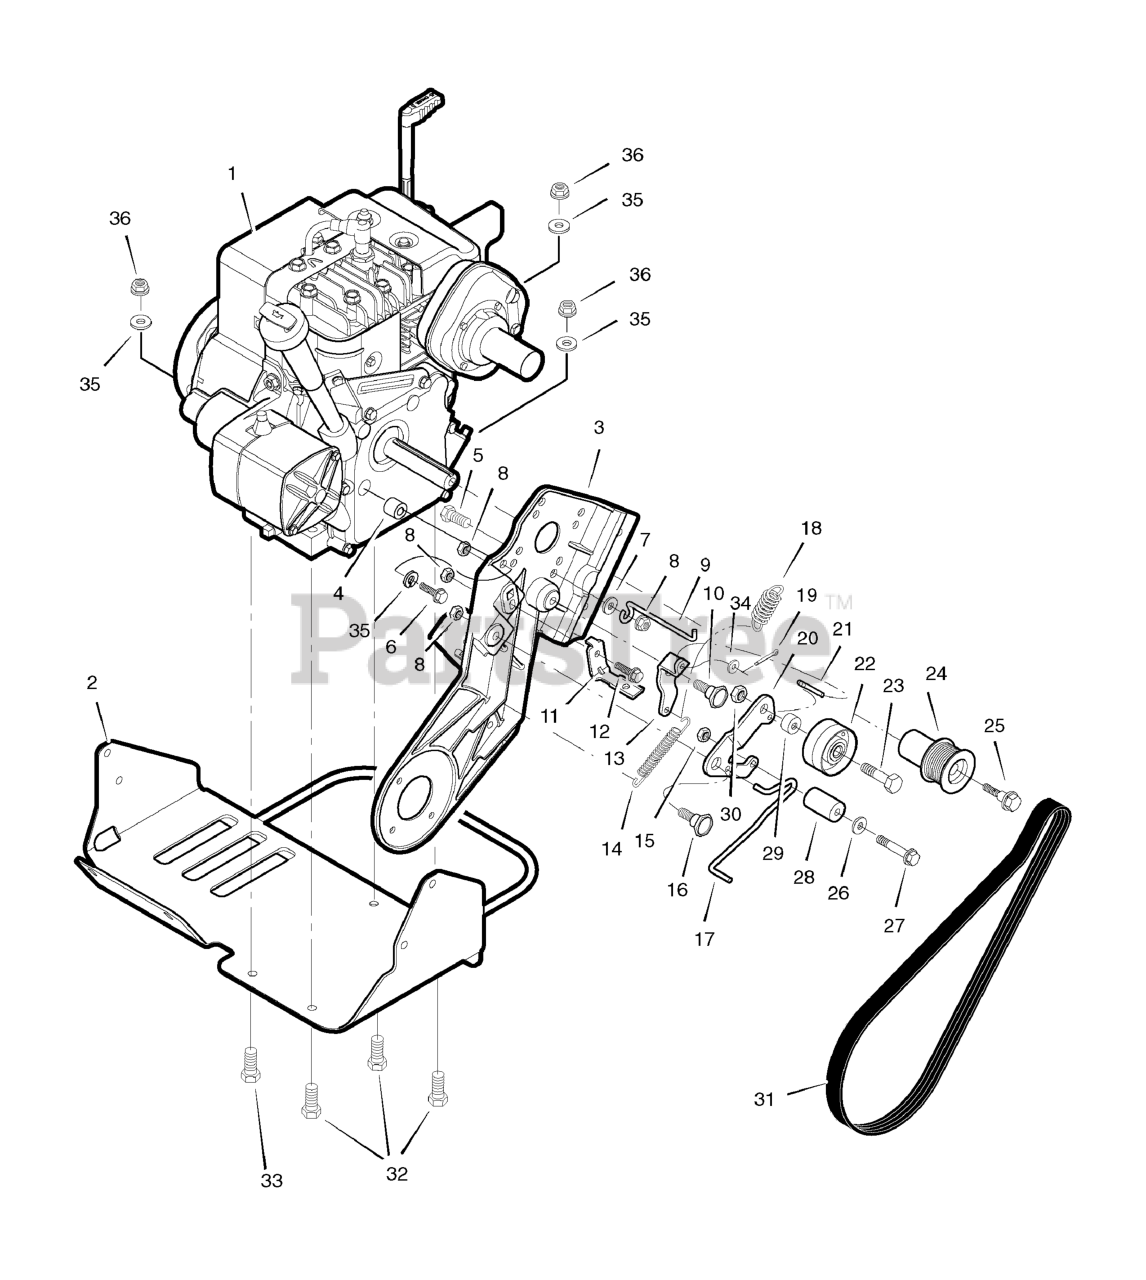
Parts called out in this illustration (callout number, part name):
1	Engine, 5HP 4CY B&S
2	Cradle Assembly, Engine
4	Antivibration Mount, Engine
5	Bolt, Hex 5/16-18 x 0.865
6	Bolt, Hex 5/16-24 x 1.1125
7	Washer, Flat
8	Locknut, Hex Center 5/16-18
9	Guide, Belt
11	Pad, Brake
12	Screw, 1/4-20 x .63
13	Idler, Arm Pivot
15	Nut Hex 1/4-20
17	Wire, Brake
19	Pin, Cotter
20	Arm, Idler
21	Rod, Clutch Linkage
22	Pulley, Idler
23	Screw, 3/8-16 x 1.62
24	Pulley, Model 9 Engine
25	Bolt, Engine Pulley
26	Washer, Flat
27	Screw, 1/4-20 x 2.00
28	Pinch Roller
29	Spacer, Idler
30	Nut, Hex
31	Belt, Drive
32	Bolt, Hex 5/16-18
33	Screw 3/8-16 x 1.00
34	Washer, Flat
35	Lockwasher, Split
36	Nut, 5/16-18
